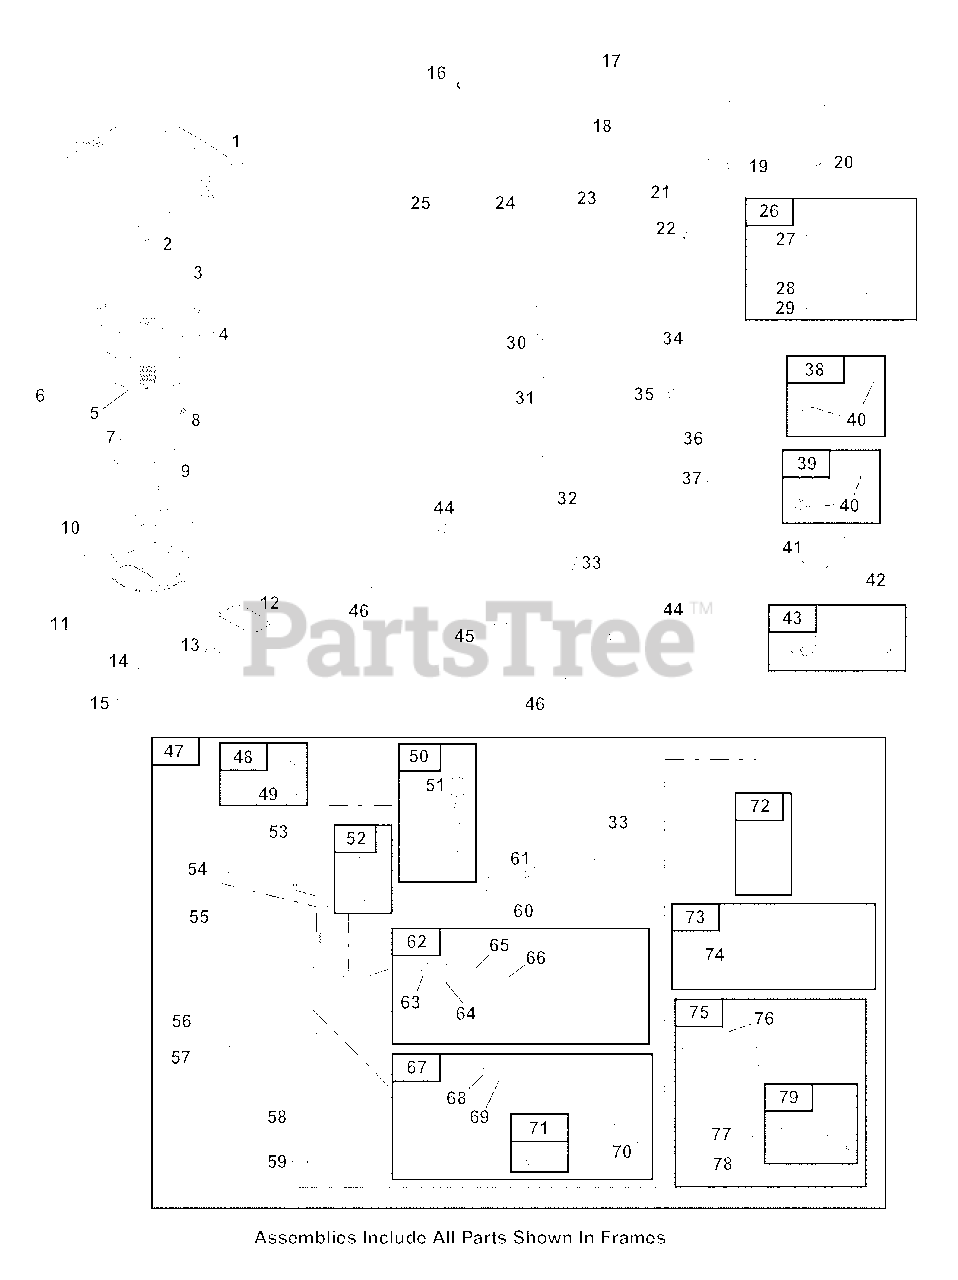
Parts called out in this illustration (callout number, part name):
1	Air Cleaner Cover
2	Air Cleaner Knob
3	Air Filter Retainer
4	Pre-Cleaner Filter
5	A/C Cartridge Filter
6	Screw (Air Cleaner Base)
7	Nut (Air Cleaner Base)
8	Screw (Carburetor Shield)
9	Carburetor Shield
10	Air Cleaner Base
12	Air Cleaner Gasket
13	Screw (Cleaner Mounting Strap)
14	Screw (Cleaner Mounting Strap)
15	Cleaner Mounting Strap
16	Bell Crank
17	Control Bracket
18	Screw (Control Bracket)
19	Governed Idle Spring
20	Governor Spring
21	Casing Clamp
22	Screw (Casing Clamp)
23	Choke Link
24	Mechanical Governor Link
25	Link Spring
26	Governor Control Lever
27	Bolt (Governor Lever)
28	Washer (Governor Control Lever)
29	Nut (Governor Control Lever)
30	Nut (Carburetor)
31	Stud (Carburetor)
32	Carburetor Spacer
33	Intake Gasket
34	Fuel Pump
35	Screw (Fuel Pump)
36	Fuel Pump Bracket
37	Screw (Fuel Pump Bracket)
38	Fuel Line (Choke Valve)
39	Fuel Line (Cut to Required Length)
40	Hose Clamp
41	Fuel Filter
42	Tube Clamp
43	Fuel Solenoid
44	Screw (Intake Manifold)
45	Intake Manifold
46	Intake Gasket
47	Carburetor
48	Carburetor Plug
49	Sealing Washer (Carburetor Plug)
50	Idle Mixture Valve
51	Limiter Cap
52	Idle Speed Kit
54	Welch Plug
55	Welch Plug
56	Choke Valve
57	Screw (Choke Valve)
58	Carburetor Nozzle
60	Throttle Valve
61	Screw (Throttle Valve)
62	Throttle Shaft Kit
63	Retaining Ring
65	Throttle Shaft Seal
66	Throttle Spacer
67	Choke Shaft Kit
68	Choke Shaft Seal
70	E Ring Retainer
71	Choke Ball Locator
72	Float Needle Valve
73	Carburetor Float
74	Float Hinge Pin
75	Float Bowl
76	Float Bowl Gasket
77	Sealing Washer (Float Bowl)
78	Screw (Bowl Float)
79	Carburetor Bowl Drain
